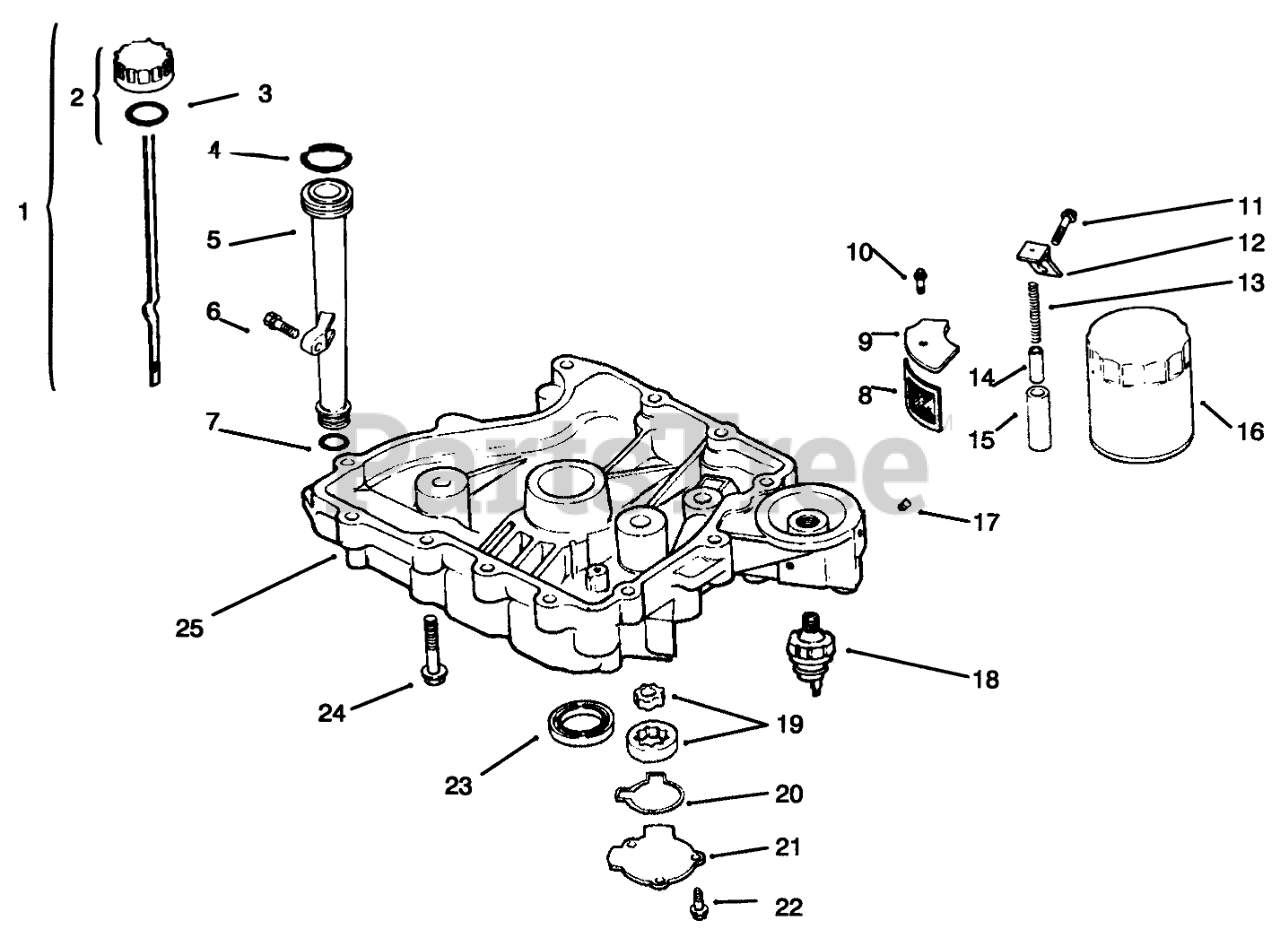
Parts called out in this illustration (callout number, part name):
1	Dipstick INC 2-3
2	Kit-Oil Fill Cap
3	"O"Ring
4	"O"Ring
5	Tube-Oil Fill
6	Screw
7	"O"Ring
8	Screen-Oil Pickup
9	Cover-Oil Screen
10	Screw-HF
11	Screw
12	Bracket-Oil Pump Relief
13	Spring-Oil Relief Valve
14	Piston-Oil Relief Valve
15	Body-Oil Relief Valve
16	Filter-Oil
17	Plug
18	Switch, pressure
19	Pump-Oil
20	"O"Ring-Pump Cover
21	Cover-Oil Pump
22	Screw-HF
23	Seal-Crankshaft
24	Screw M8x1.25x45
25	Pan-Oil
